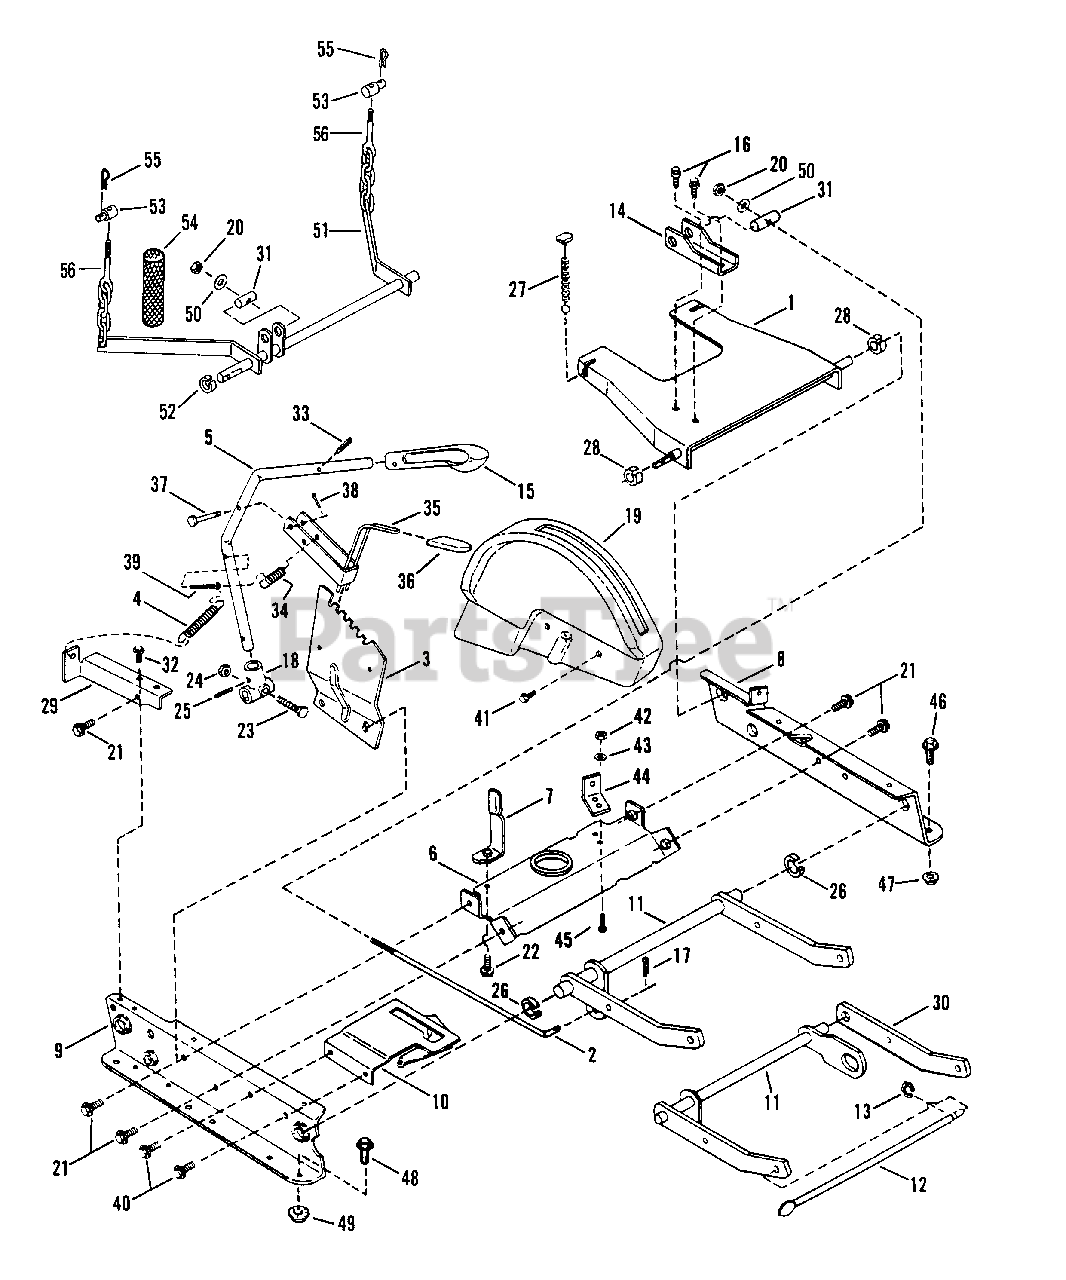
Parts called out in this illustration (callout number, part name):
1	ARM, Rear Lift
2	ROD, Leveling
3	QUADRANT, Lift Lever
4	SPRING, Extension
5	LEVER, Lift
6	BRACE, Top
7	GUIDE, Belt
8	RAIL, Left Hand
9	RAIL, Right Hand
10	ASSEMBLY, Clutch Plate
11	ARM, Front Lift, Non-Adjustable
11	ARM, Front Lift, Adjustable
12	ROD, Support
13	RING, 7/16 Retaining
14	ARM, Leveling
15	GRIP, Height Adjustment Lever
16	SCREW, 5/16-18 x 5/8" Self-Tapping (Torx)
17	PIN, 1/8 x 3/4" Cotter
18	HUB, Deck Lift
19	COVER, Height of Cut
20	NUT, 3/8-24 Hex Nyloc
21	SCREW, 3/8-16 x 5/8" Self-Tapping
22	SCREW, 5/16-18 x 5/8" Self-Tapping
23	BOLT, 5/16-24 x 1-5/8" Tapered Axle
24	NUT, 5/16-24 Hex Flange lock
25	PIN, 3/16 x 1" Roll
26	RING, Red
27	CABLE, Rear Deck
28	RING, White
29	BRACKET, Deck Lift
30	ARM, Front Lift - Left
31	PIVOT, Leveling
32	SCREW, 1/4-20 x 3/8" Self-Tapping
33	PIN, 3/16 x 3/4" Roll
34	SPRING, Latch
35	LATCH
36	GRIP, Lift Latch
37	PIN, 1/4 x 1-1/4" Clevis
38	PIN, 1/16 x 3/4" Cotter
39	PIN, 3/16 x 1 1/2" Cotter
40	SCREW, 5/16-18 x 1/2" Self-Tapping
41	SCREW, 1/4-20 x 5/8" Self-Tapping
42	NUT, 5/16-24 Hex
43	WASHER, 5/16 Internal Tooth Lock
44	ANCHOR
45	SCREW, 5/16-24 x 3/4" Hex Head Cap
46	BOLT, 5/16-18 x 5/8" Hex Flange Lock
47	NUT, 5/16-18 Hex Flange Lock
48	BOLT, 1/4-20 x 1/2" Hex Flange Lock
49	NUT, 1/4-20 Hex Flange Lock
50	WASHER, 3/8" Flat
51	ARM, Rear Lift
52	RING Blue
53	SWIVEL
54	COVER, Chain
55	PIN, 3/32 x 1-1/2" Hair
56	EYE BOLT
